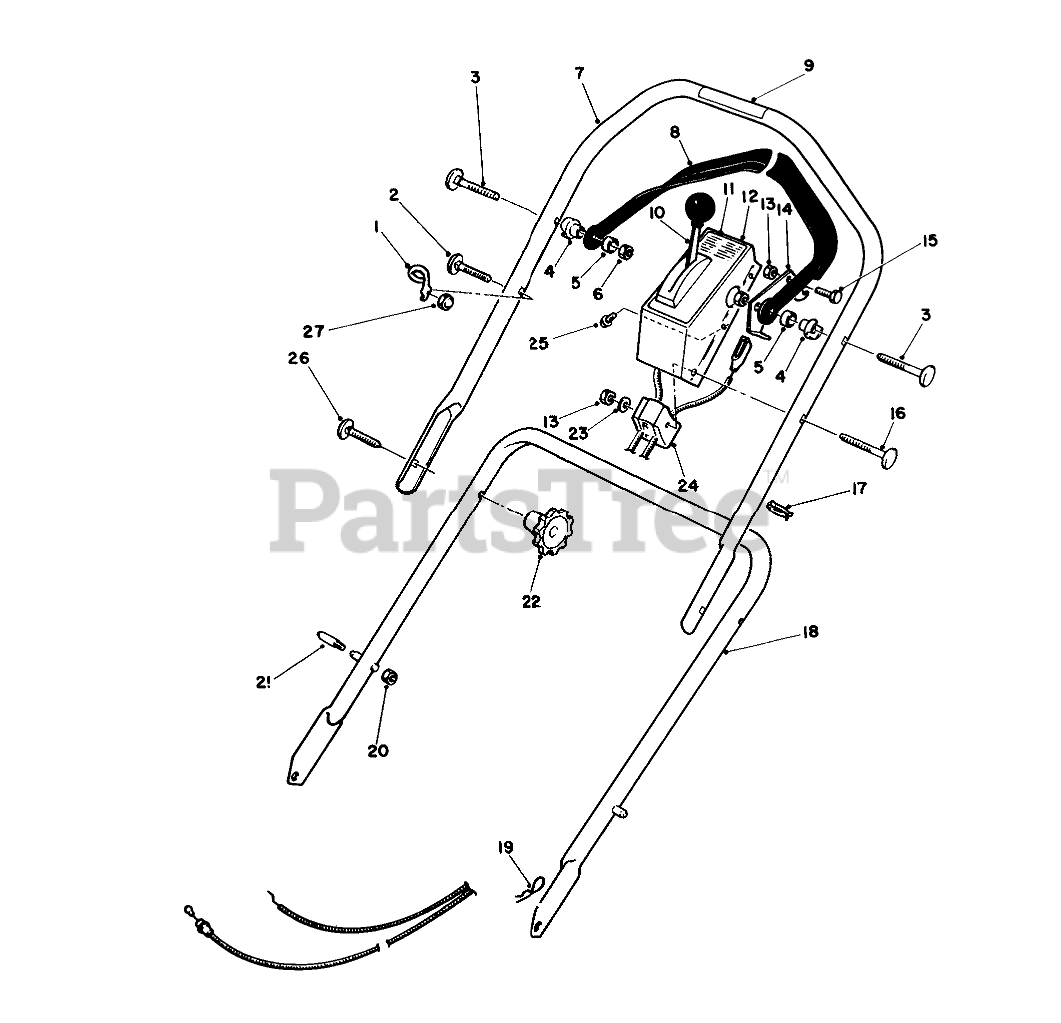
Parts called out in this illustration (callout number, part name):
1	Guide
2	HANDLE SCREW
3	5/16-18 X 2 HNDLE SCREW
4	SPACER-SUPPORT
5	SPACER-NYLON
6	NUT-LOCK, NI
7	Handle-Upper (Incl. Ref. #9)
8	Bar-Control
9	DANGER DECAL
10	THROTTLE CONT-SERVICE
11	Decal-Control Cover
12	Cover-Control (Incl. Ref. #11)
13	NUT-LOCK, NI
14	Lever-Control
15	SCREW-HH
16	SCREW-HANDLE
17	BOWDEN CLIP
18	LOWER HANDLE ASM
19	PIN-COTTER, HAIR
20	NUT-LOCK, NI
21	HANDLE PIN
23	WASHER-FLAT
24	SUPPORT-CABLE
25	SCREW-HWHTF
26	5/16-18 X 2 HNDLE SCREW
27	NUT-CAP
